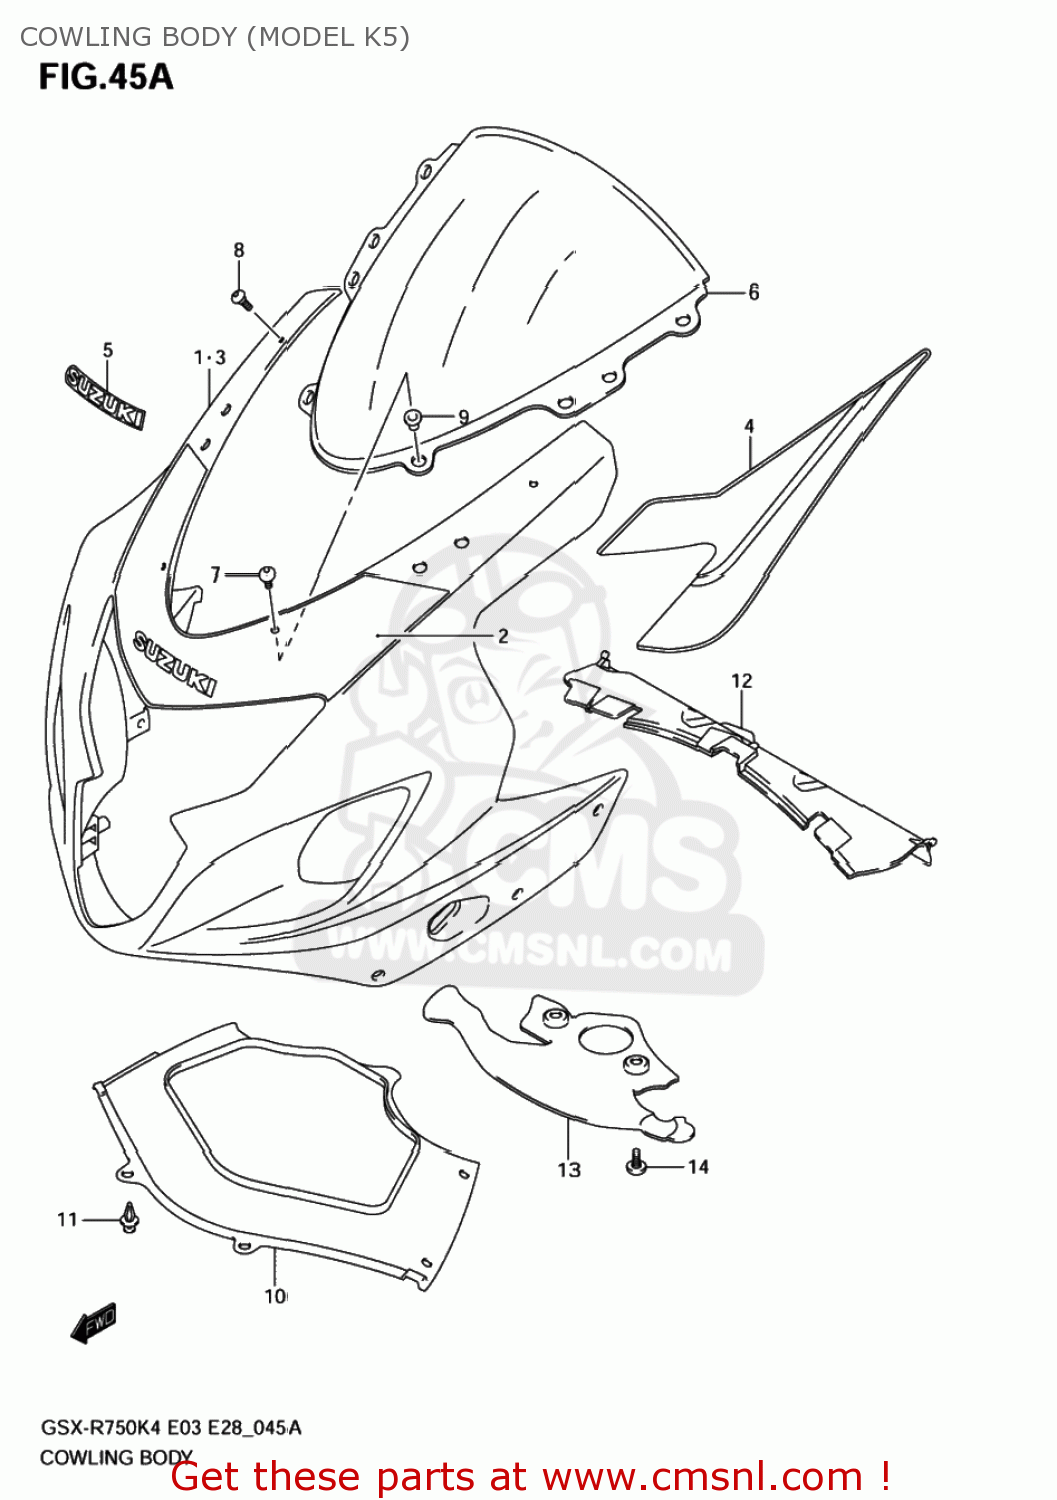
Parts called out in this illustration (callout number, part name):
1	COWLING ASSY,BODY(BLUE)
2	TAPE,COWL BODY FR
3	COWLING ASSY,BODY
4	TAPE SET,COWL BODY
5	EMBLEM,SUZUKI
6	WINDSCREEN
7	SCREW(5X18)
8	SCREW(5X15)
9	NUT
10	COVER,BODY COWLING
11	CLIP(BLACK)
12	COVER,COWLING FR LWR
13	COVER,LWR BRACKET
14	BOLT
